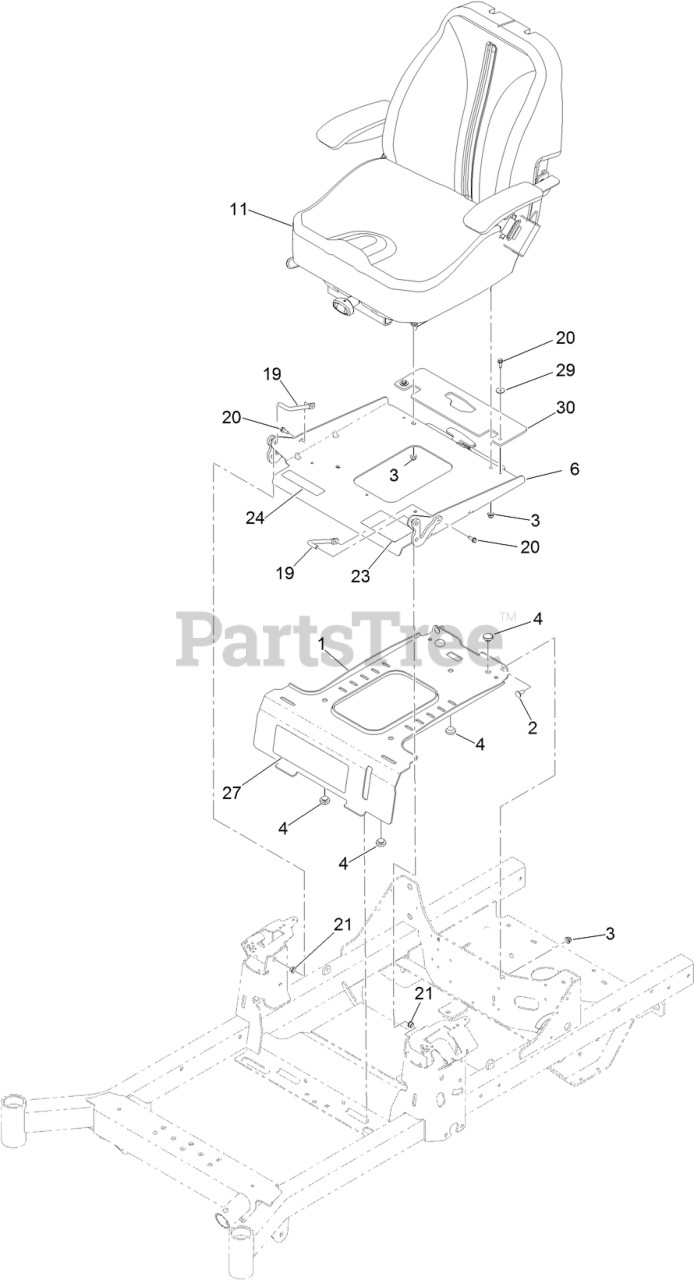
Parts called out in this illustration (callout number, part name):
1	PLATE-RETAINER, TANK
2	SCREW-CARR
3	NUT-HF, NI
4	BUMPER-SEAT
6	SEAT PAN AND LATCH ASM
11	SEAT ASM
19	PIN-PIVOT, SEAT
20	SCREW-HWH, THREAD ROLL
21	BUSHING-FLANGED
23	DECAL-AID, SERVICE
24	DECAL-LATCH, SEAT
29	WASHER
30	GUARD-SEAT, RUBBER
